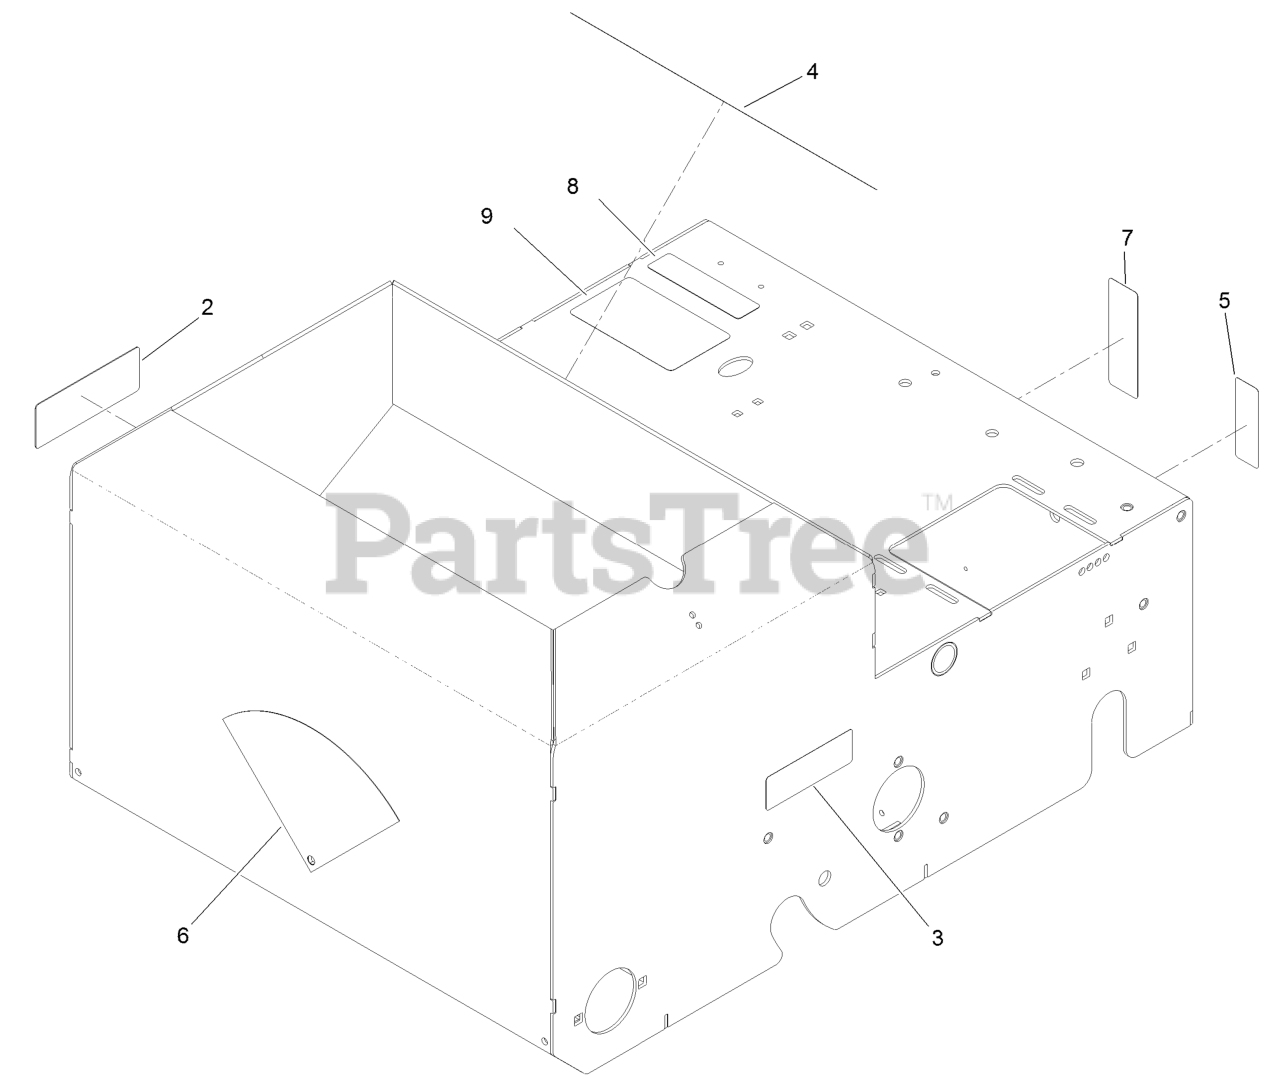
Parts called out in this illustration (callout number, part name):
2	DECAL-DANGER
3	DECAL-WARNING
4	DECAL-WARNING
5	DECAL-BRAKE, PARKING
6	DECAL-FLOW, SEED
7	DECAL-BYPASS
8	DECAL-ARRESTER, SPARK
9	Decal-Service Aid Seeder
